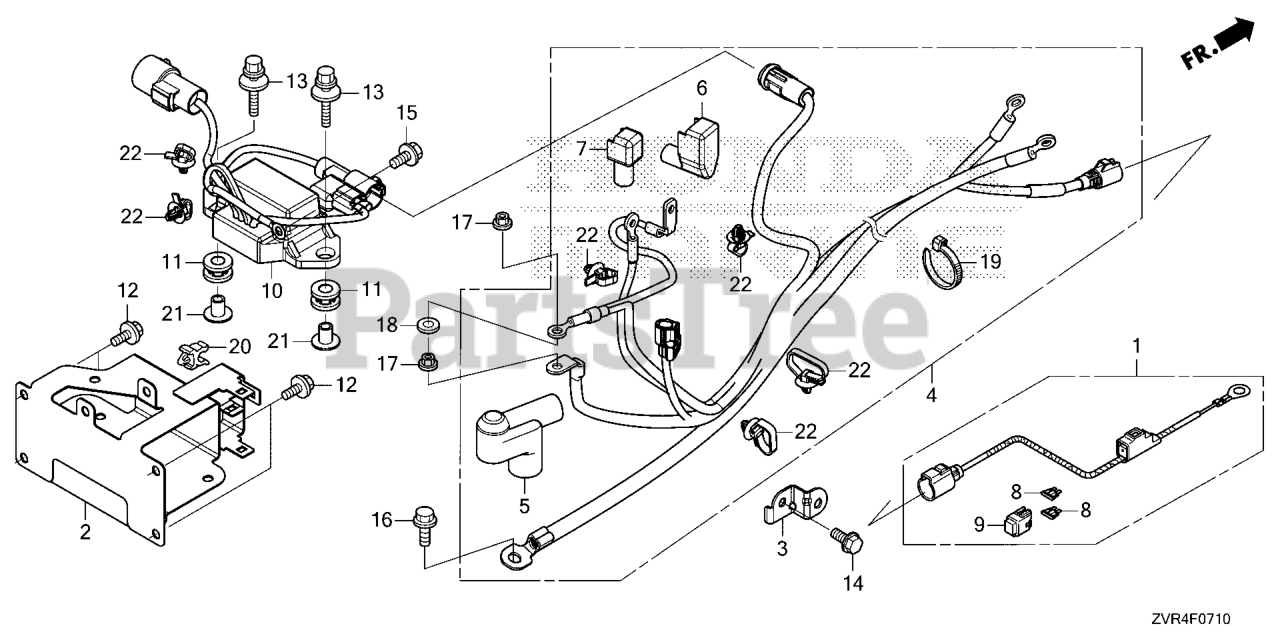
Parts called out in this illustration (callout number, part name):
1	HARNESS ASSY., POWER
2	BRACKET, CONNECTOR A
3	BRACKET, CLIP B
4	CABLE ASSY., START
5	COVER, STARTER TERMINAL
6	COVER B, TERMINAL (L)
7	COVER B, TERMINAL
8	FUSE, BLADE (40A)
9	COVER ASSY., FUSE (40A)
10	RELAY, POWER TILT
11	GROMMET, RELAY
12	BOLT, FLANGE (6X14) (CT200)
13	BOLT-WASHER (6X25)
14	BOLT, FLANGE (6X14)
15	BOLT, FLANGE (6X12)
16	BOLT, FLANGE (8X18)
17	NUT-WASHER (8MM)
18	WASHER, PLAIN (8MM)
19	BAND, WIRE (165MM) (BLACK)
20	CLIP, FUEL TUBE (14) (NOT AVAILABLE)
21	COLR, CDI UNIT CASE
22	CLIP, HARNESS BAND (145MM) (BLACK)
